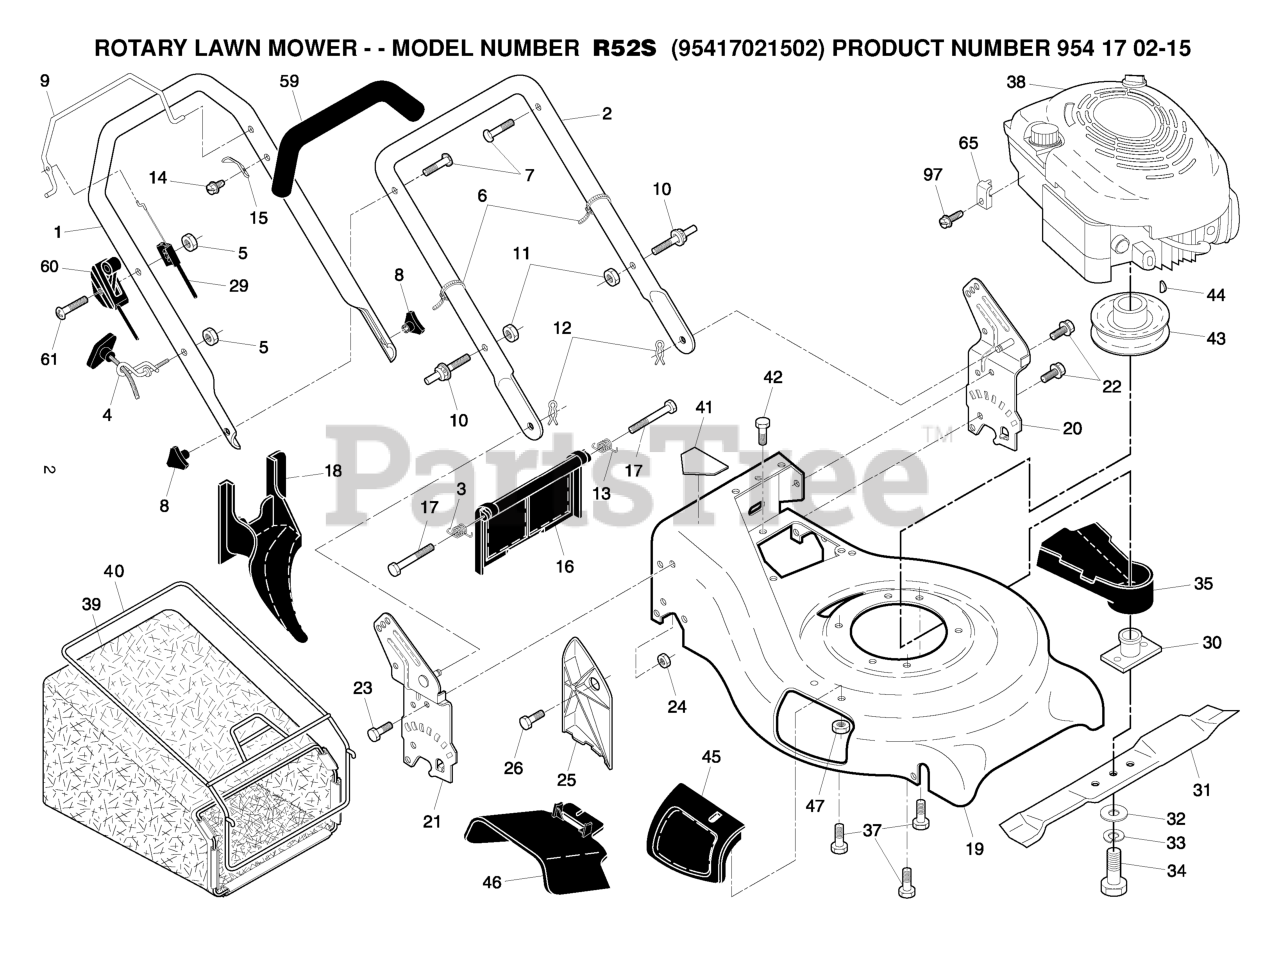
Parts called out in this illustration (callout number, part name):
1	HANDLE.UP.DLX.COMF.W/GRIP.GREY
2	HANDLE.LOWER.21.GREY
3	SPRING.LH.REAR.DOOR.21.RWGD
4	RB GUIDE.ROPE.STD.BLK.ZIN WSL
5	NUT
6	TIE GUIDE
7	BOLT, HANDLE 5/16-18X1.75
11	NUT.CENTERLOCK.5/16-
12	HAIRPIN COTTER
13	SPRING.RH.REAR.DOOR.21.RWGD
15	BRACKET UPSTOP
16	DOOR.REAR.PLASTIC.21.RWGD.BLAC
18	PLUG.MULCHER.RGD.21.
20	BRKT.ASM.HNDL.21.RWGD.LT
21	BRKT.ASM.HNDL
22	SELF-TAPPING SCREW 5/16-18X3/4
23	BOLT, HEX HEAD 5/16-18
24	NUT.71038.31-18.HEX.NYLOCK
25	CLIPPING DEFLECTOR
29	ENGINE ZONE CONTROL
30	ADAPTER.BLADE
32	WASHER,HARDEN
33	LOCKWASHER
34	SCREW, HEX HD 3/8-24 X 1-3/8
37	BOLT 3/8-16X1-1/8
40	FRAME.CATCHER.21.RGD.AG
41	DECAL.INTERNATIONL.CUTFINGER
43	HI-PRO KEY
44	PULLEY.ENG.25MMM
45	MULCHER DOOR ASM.
46	DEFLECTOR
59	GRIP.HANDLE.FOAM
60	CONTRL.THROTTLE.
65	CABLE CLAMP(ENGINE)
97	SCREW.HEX.HEAD.WASHER.10-16
